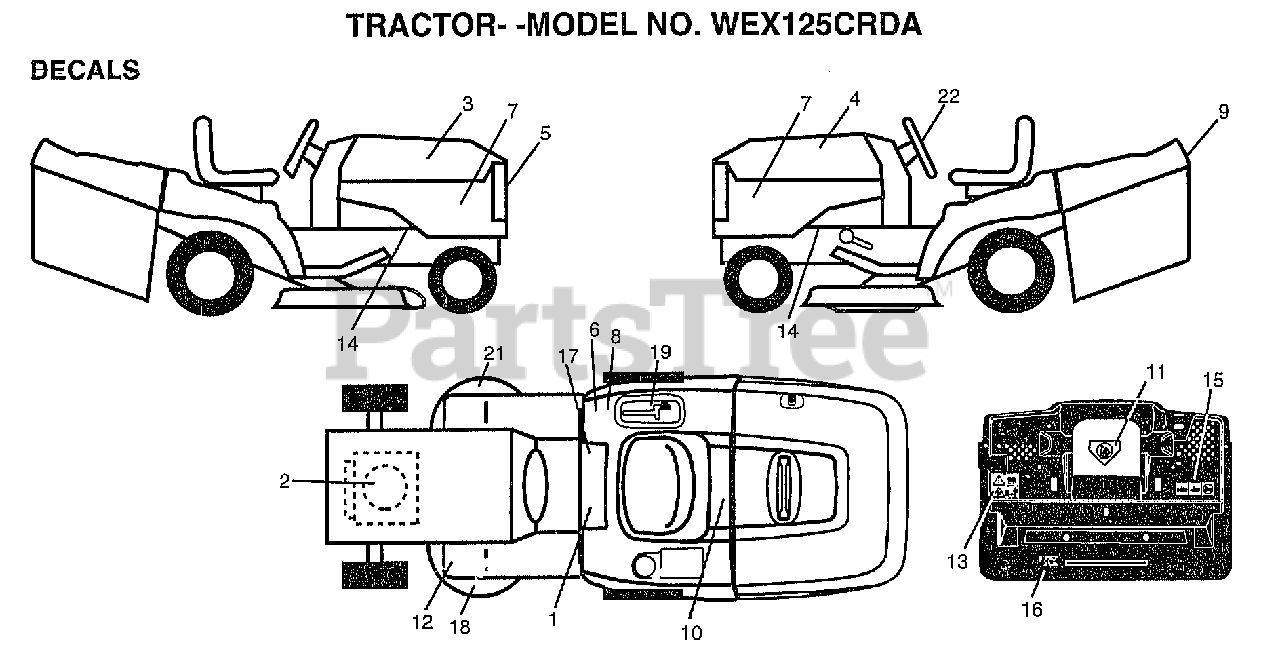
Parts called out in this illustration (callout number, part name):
1	DECAL.READ.O.MANU
2	DECAL.ENG.B&S
3	DECAL.HOOD.RH.
4	DECAL.HOOD.LH
5	DECAL, GRILLE LENS
7	DECAL, PANEL SIDE LOGO
8	DECAL.EURO.ST.CE.
9	DECAL.FENDER.LOGO
10	DECAL.BATRY.3-3908
11	DECAL.DANGER.CUTF
12	DECAL-BRAKE/CLUTC
13	DECAL.WARNING.BACKPLATE.CRD
14	"DECAL CHASSIS,HOT"
15	DECAL, OPER BAG
16	DECAL.DRAWBAR.LDL
17	DECAL BRAK PARK
18	DECAL, DECK GRASSEATER
19	DECAL.CONSOLE.6SP.CRD
21	DECAL.DECK.HEX.BELT
22	DECAL, INS STRG WH
